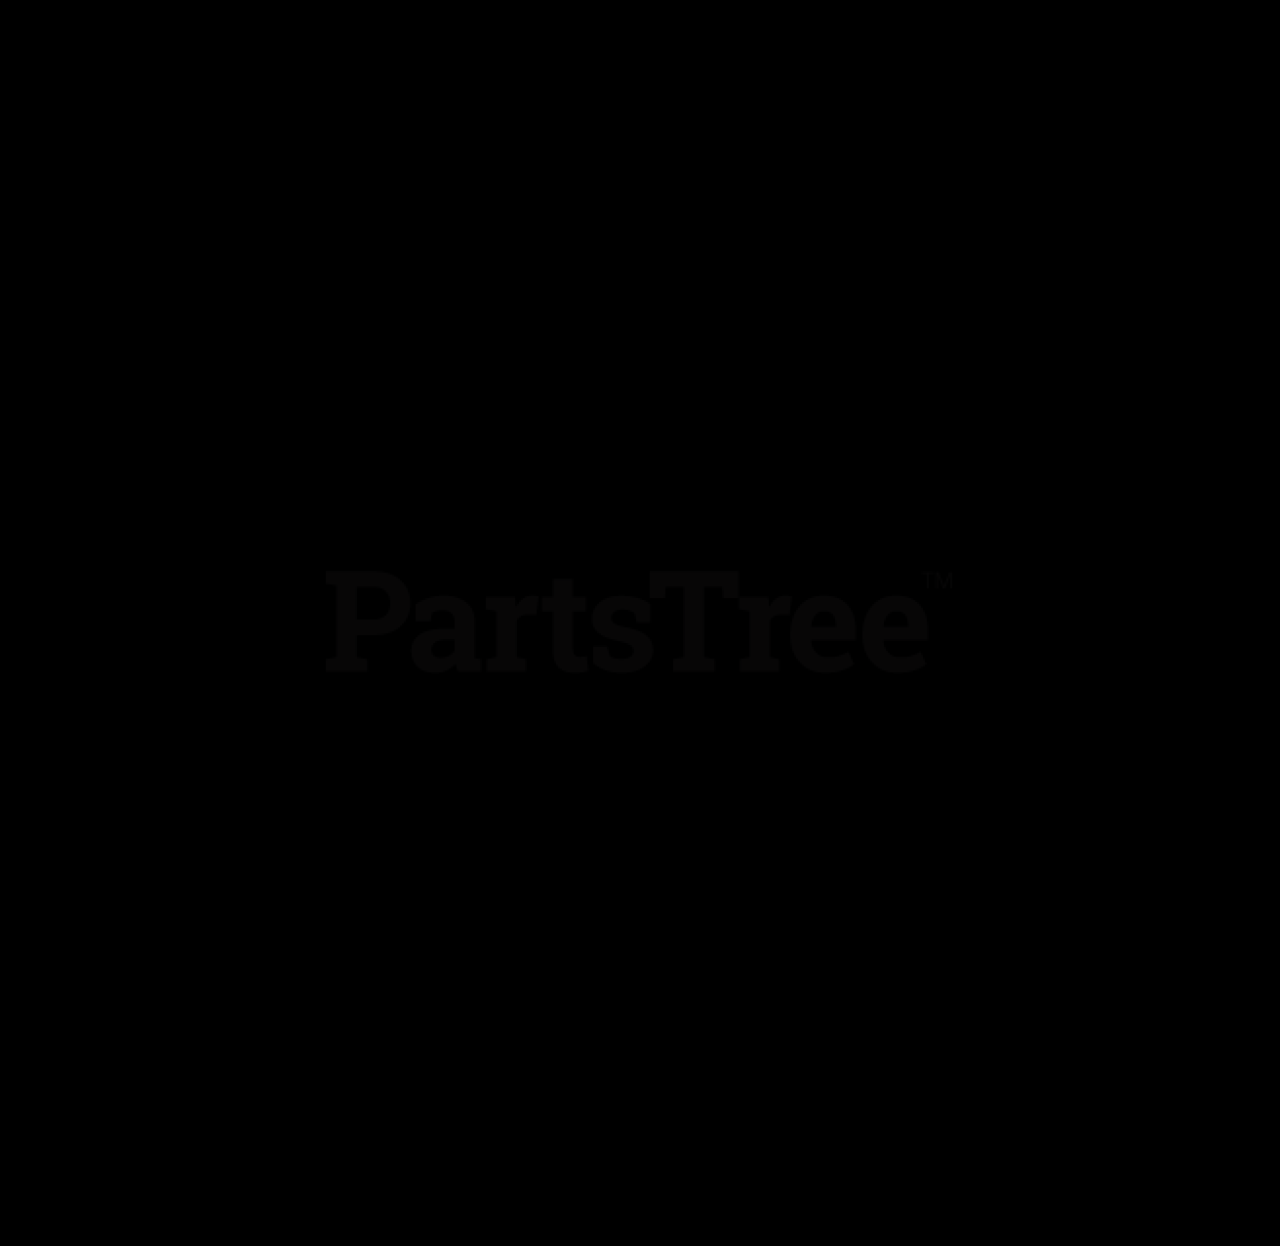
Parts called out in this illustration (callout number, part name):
1	ROPS, PM200 Replacement Kit
2	Bolt, Hex .50-13 x 3.50 Grade 5
3	Assembly, ROPS PIN/LANYARD
4	Nut, Locking-Top-Flange .50-13
5	Bumper, ROPS Rubber
6	Bracket, ROPS Stop, Pro-Master
7	Bolt, Hex .50-13 x 3.00 Grade 5
